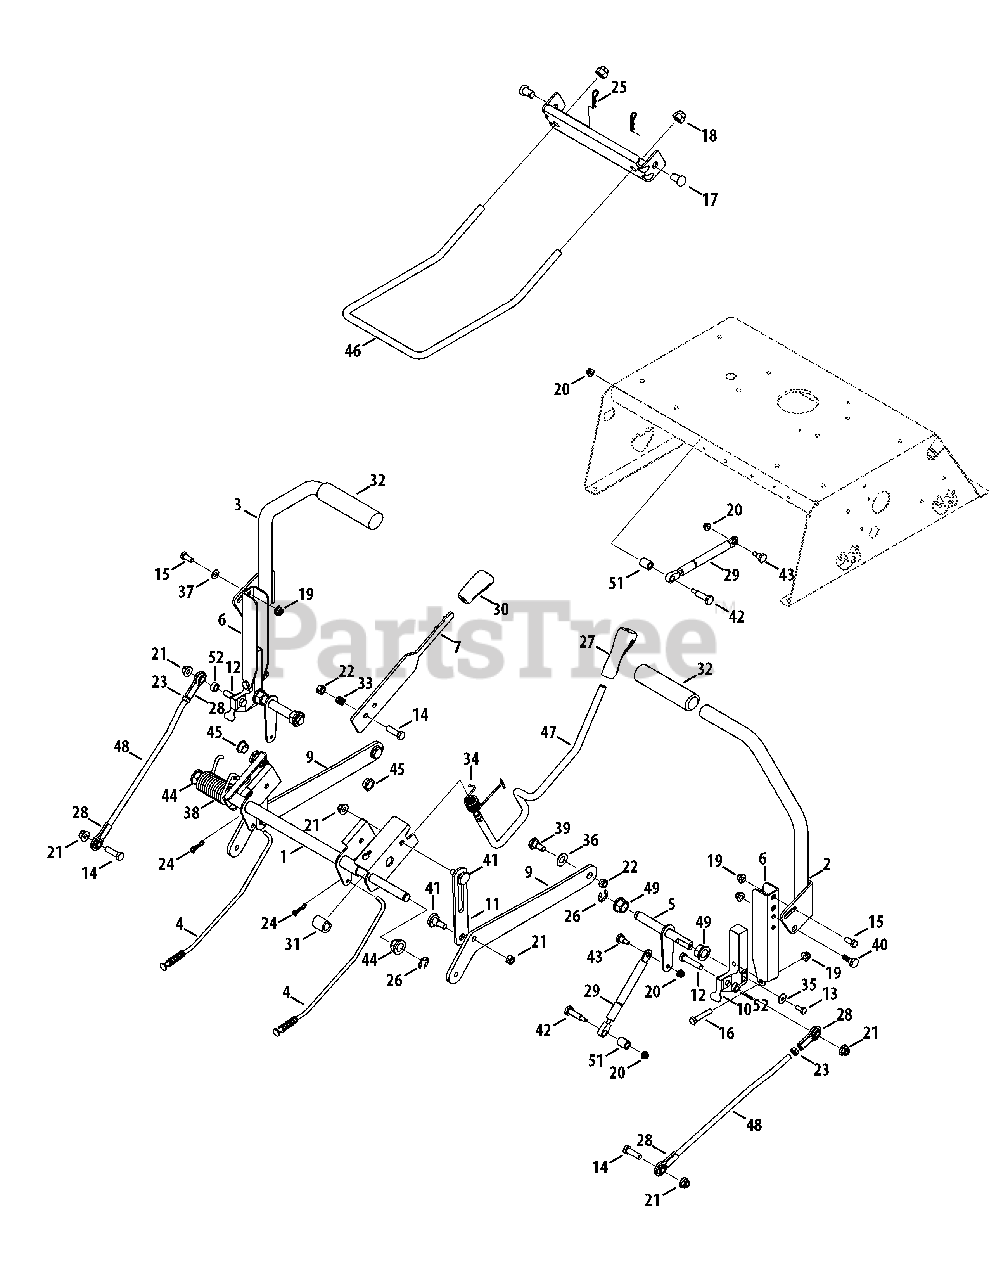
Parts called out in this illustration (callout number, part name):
1	Deck Lift Shaft Assembly
2	Lapbar Lever RH
3	Lapbar Lever LH
4	Brake Rod (42" & 50" Decks)
5	Control Shaft
6	Lapbar Pivot Bracket
7	Brake Handle
8	Front Deck Hanger Bracket
9	Deck Lift Arm
10	Switch Actuator Bracket
11	Lift Link Plate
12	Hex Screw, 3/8-16 x 1.75
13	Hex Lock Screw, 1/4-20 x .62
14	Hex Cap Screw, 3/8-16 x 1.25
15	Hex Cap Screw,5/16-18 x .75
16	Hex Cap Screw,5/16-18 x 1.75
17	Clevis Pin, .50 x .78
18	Hex Nut, 1/2-13
19	Hex Flange Insert Lock Nut,5/16-18
20	Hex Flange Insert Lock Nut, 1/4-20
21	Hex Flange Insert Lock Nut, 3/8-16
22	Hex Lock Nut, 3/8-16
23	Jam Nut, 3/8-24
24	Bow-Tie Cotter Pin
25	Cotter Pin
26	E-Ring, .625 Dia.
27	Handle Grip
28	Rod End
29	Damper Cylinder
30	Handle Grip
31	Spacer, .62 x 1.0
32	Hand Grip
33	Compression Spring
34	Torsion Spring
35	Bell Washer, .265 x .75 x .062
36	Flat Washer, .51 x 1.0 x .06
37	Flat Washer, .344 x .688 x .065
38	Torsion Sprg., LH (50" & 54" Decks)
39	Shoulder Screw, .498 x .340 x 3/8-16
40	Shoulder Screw, .437 x .268 x5/16-18
41	Shoulder Screw, .5 x .434 x 3/8-16
42	Shoulder Screw, .374 x 1.16 x 1/4-20
43	Shoulder Screw, .375 x .38 x 1/4-20
44	Hex Flange Bearing
45	Flange Bearing, .626 x .938 x .344
46	Deck Front Hanger Rod
47	Deck Lift Handle Rod
48	Lapbar Control Rod
49	Hex Flange Bearing
50	Control Hub
51	Spacer, .385 x .630 x .75
52	Spacer, .380 x .625 x .265
